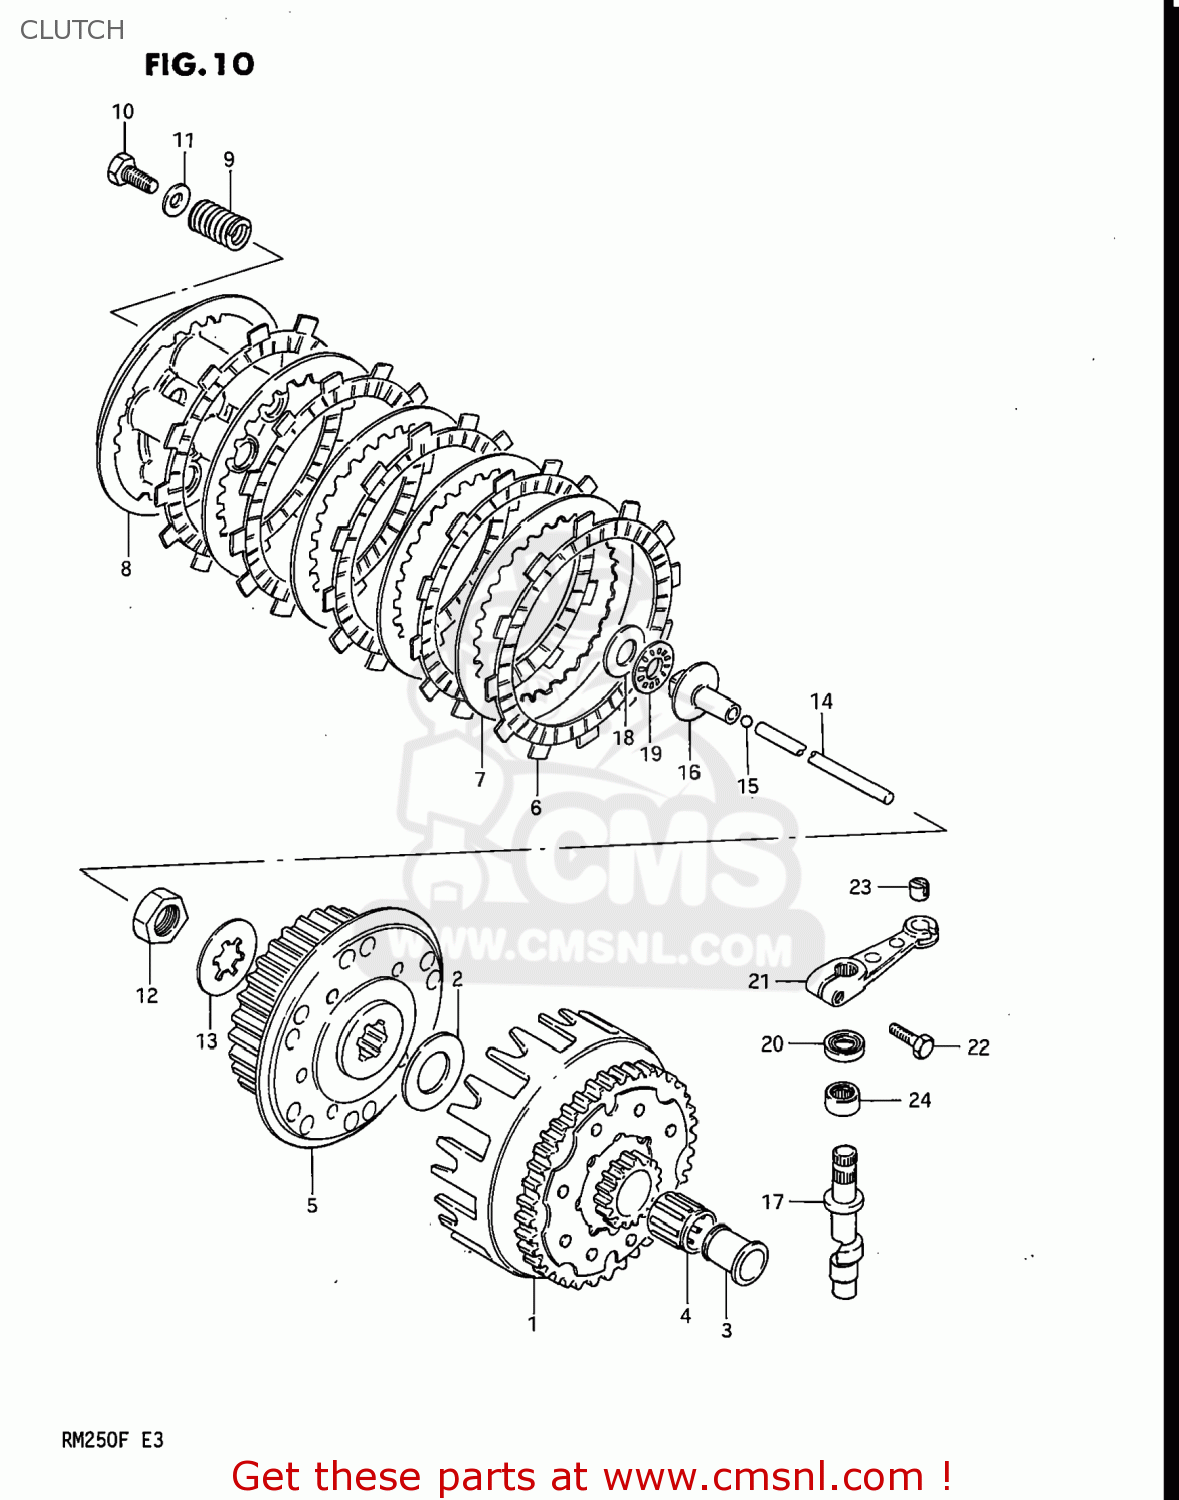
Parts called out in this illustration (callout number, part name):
1	GEAR ASSEMBLY,PRIMARY DRIVE
2	WASHER(20X38X2)
3	SPACER
4	BEARING
5	HUB,CLUTCH SLEEVE
6	PLATE,CLUTCH DRIVE (MCA)
7	PLATE,CLUTCH DRIVEN (NAS)
8	DISC,CLUTCH PRESSURE
9	SPRING
10	BOLT, UPPER
11	WASHER
12	NUT (20MM)
13	WASHER,LOCK
14	ROD,CLUTCH PUSH
15	BALL
16	PIECE,CLUTCH PUSH
17	SHAFT,CLUTCH RELEASE C
18	WASHER
19	BEARING(15X28X2)
20	SEAL,OIL(12X19X5)
21	ARM,CLUTCH RELEASE
22	BOLT
23	PIECE,RELEASE ARM END
24	BEARING(12X19X12)
